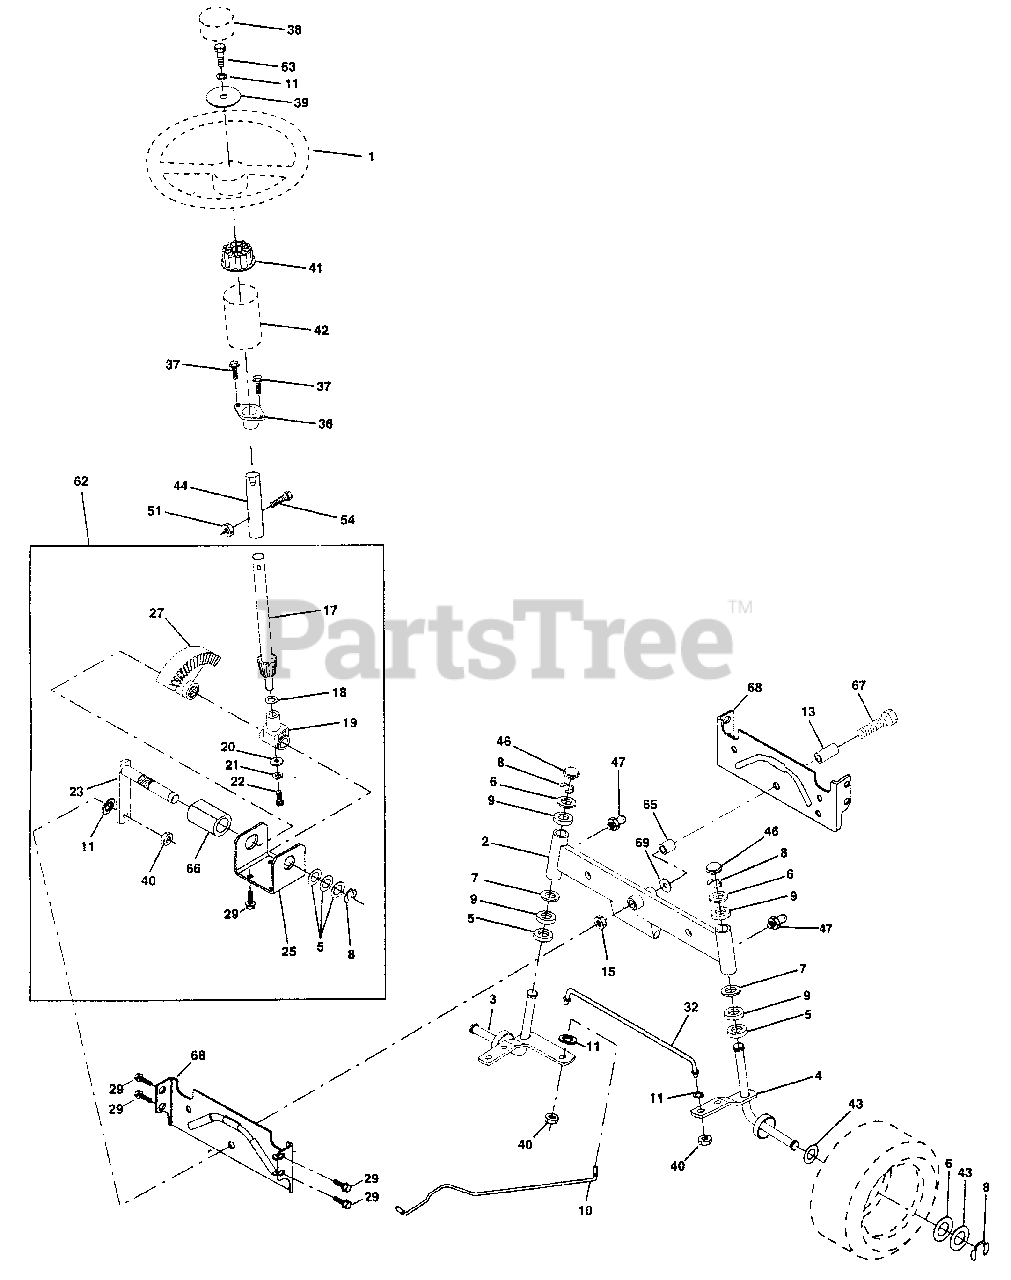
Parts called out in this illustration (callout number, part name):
1	Wheel Steering
2	Axle Front Casting Machined
3	Spindle Asm LH
4	Spindle Asm RH
5	Bearing Race Thrust Harden
6	Washer 25/32 X 1-5/8 X 16 Ga
7	Washer 27/32 X 1-1/4 X 16 Ga
8	Ring Klip #t5304-75
9	Bearing Col Strg Blk
10	Link Drag Extended Cast
11	Washer Lock Hvy Hlcl Spr 3/8
13	Bearing Axle STLT/GT
15	Nut Lock Flange 5/8-11 Unc
17	Shaft Asm Strg
18	Washer Thrust 515x 750x 033
19	Support Shaft
20	Washer Shim 1/4 X 5/8 X 062
21	Washer Lock Hvy Helical 1/4
22	Screw Cap Sckt Hd Phos & Oil
23	Shaft Asm Pittman
25	Bracket Steering
27	Gear Sector
29	Screw Thdrol 3/8-16x3/4 Ty-tt
32	Rod Asm Tie Ball
36	Bushing Strg
38	Insert Cap Strg Wh Au
39	Washer 13/32 X 2-3/8 X 8 Ga
40	Lock nut
41	Adaptor Wheel Strg
42	Boot Steering Shaft
43	Washer 25/32 X 1 1/4 X 16 Ga
44	Extension Steering Shaft LR/LT
46	Cap Spindle Fr Top Blk
47	Fitting Grease
51	Nut Lock Hex w/Ins 5/16-18
54	Bolt Fin Hex 5/16-18 Unc x 1-1/4
62	Kit, Steering Assembly Svc
63	Bolt Fin Hex 3/8-16unc x 1 Gr. 5
65	Spacer Axle
66	Bearing Arm Pittman
67	Bolt, Fin Hex 5/8-11 UNC x 2-3/4
68	Axle, Brace
69	Washer 21/32 x 1 x 16 Ga.
